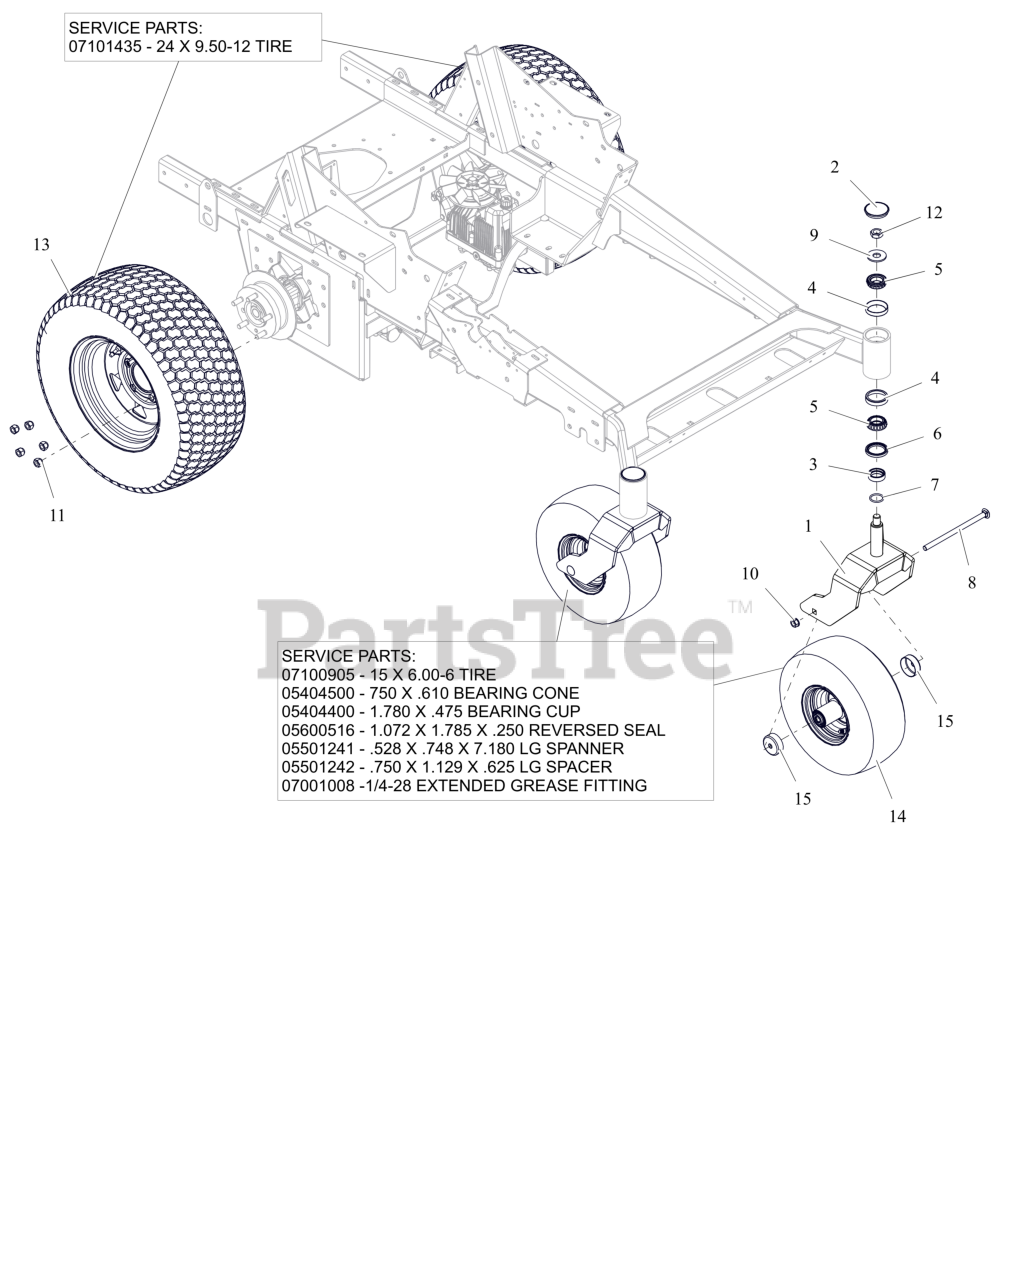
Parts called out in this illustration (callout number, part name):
1	WLDMT, CASTER FORK (RED)
2	CAP, DUST
3	SPCR, FRONT CASTER FORK
4	BRG-CUP 2.328X.465
5	BRG-CONE 1.25X.66
6	SEAL, OIL 1.75 X 2.332 X .312
8	BTL,RHSN .500-13 X 9 G5 ZCC
9	WSHR-FL-STL 0.812X2X0.148 ZCC
10	NUT-LK-CTR-FLG .500-13 GG ZCC
11	NUT, WHEEL .50-20 ZCC
12	NUT, JAM-TOPLOCK .750-16 ZCC
13	ASM-WHL/TIRE24X9.5-12 RAD BK
13	TUBE 22,23&24X8.50/9.50/10.00/10.50/12.00-12
14	ASM-WHL/TIRE15X6.00-6 SMTH BLK
14	TIRE, 15X6-6 SMOOTH
14	BRG-CONE .750X.61
14	BRG-CUP 1.781X.475
14	SEAL,1.072X1.785X.250 REVERSED
14	SPANNER, .528X.748X7.18 LG
14	SPACER, .750X1.129X.625 LG
14	GREASE FITTING 1/4-28 EXTENDED
14	TUBE 15X6-6
15	SHIELD, WHEEL BEARING
